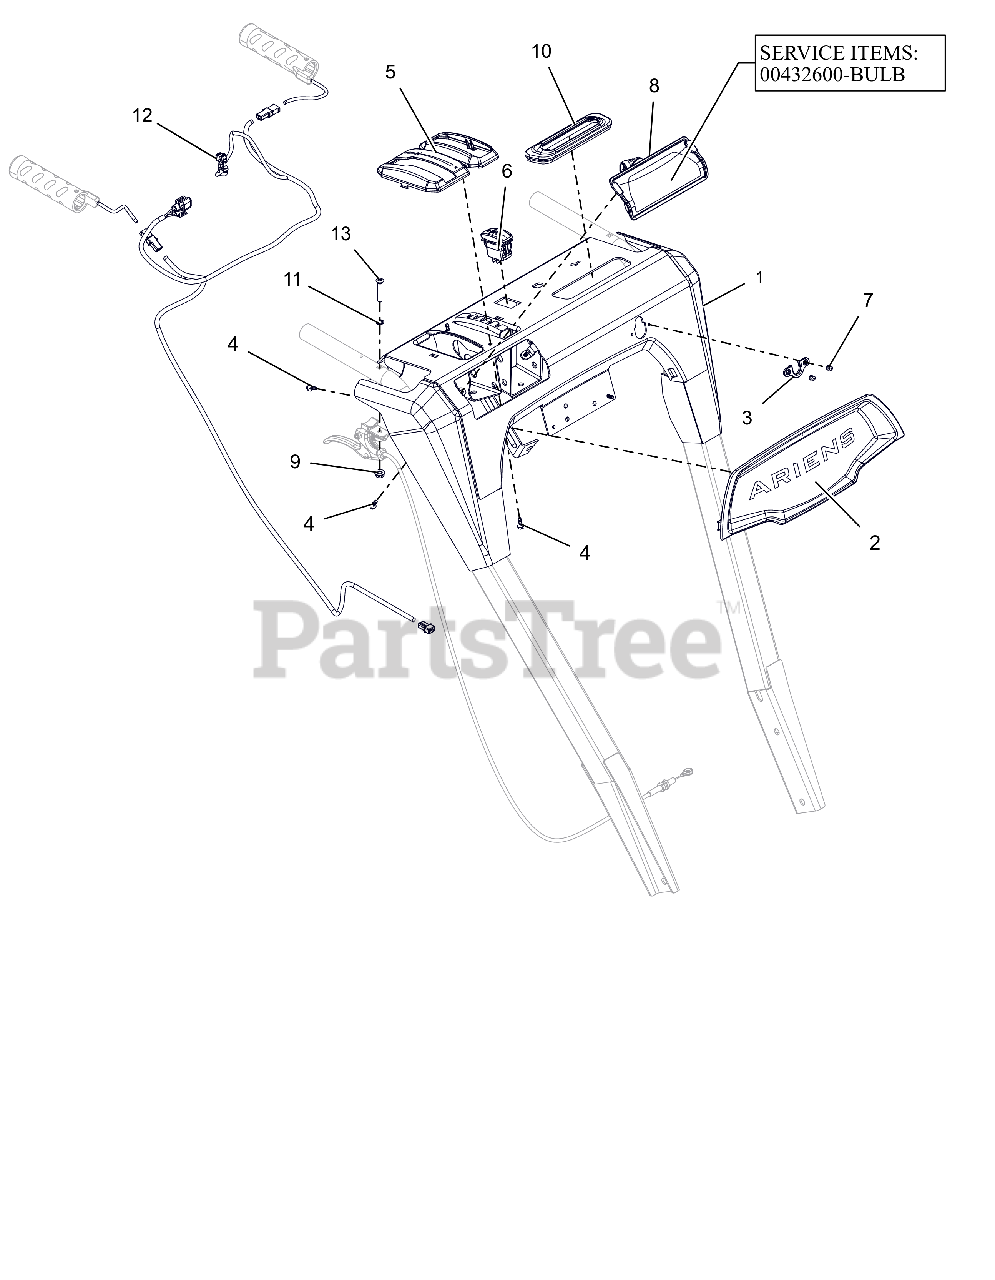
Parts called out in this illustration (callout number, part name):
1	PANEL, DASH-HYDROTRACK W/DECAL
2	BEZEL, DASH - ARIENS LG DASH
3	GROMMET, CABLE, QUICK TURN 2
4	SCR-TAP #10X.50 BOSS INDHXHD
5	BEZEL, SHIFT - HYDRO SNOW
6	SWITCH,ROCKER SPST-ON/OFF
7	RVT-POP #43 .125X.313 STL ZINC
8	HEADLIGHT ASY, HALO 20W 2SHOT
8	BULB, LIGHT-HALOGEN 20W
9	@NUT-LK-CTR-FLG .25-20 YWZC
10	GROMMET, BOOT, QUICK TURN
11	WSHR-LK-INT .250 TH TYA
12	HARNESS, LIGHT & WARMER
13	SCR-MCH .25-20X1.50 OVAL HD
